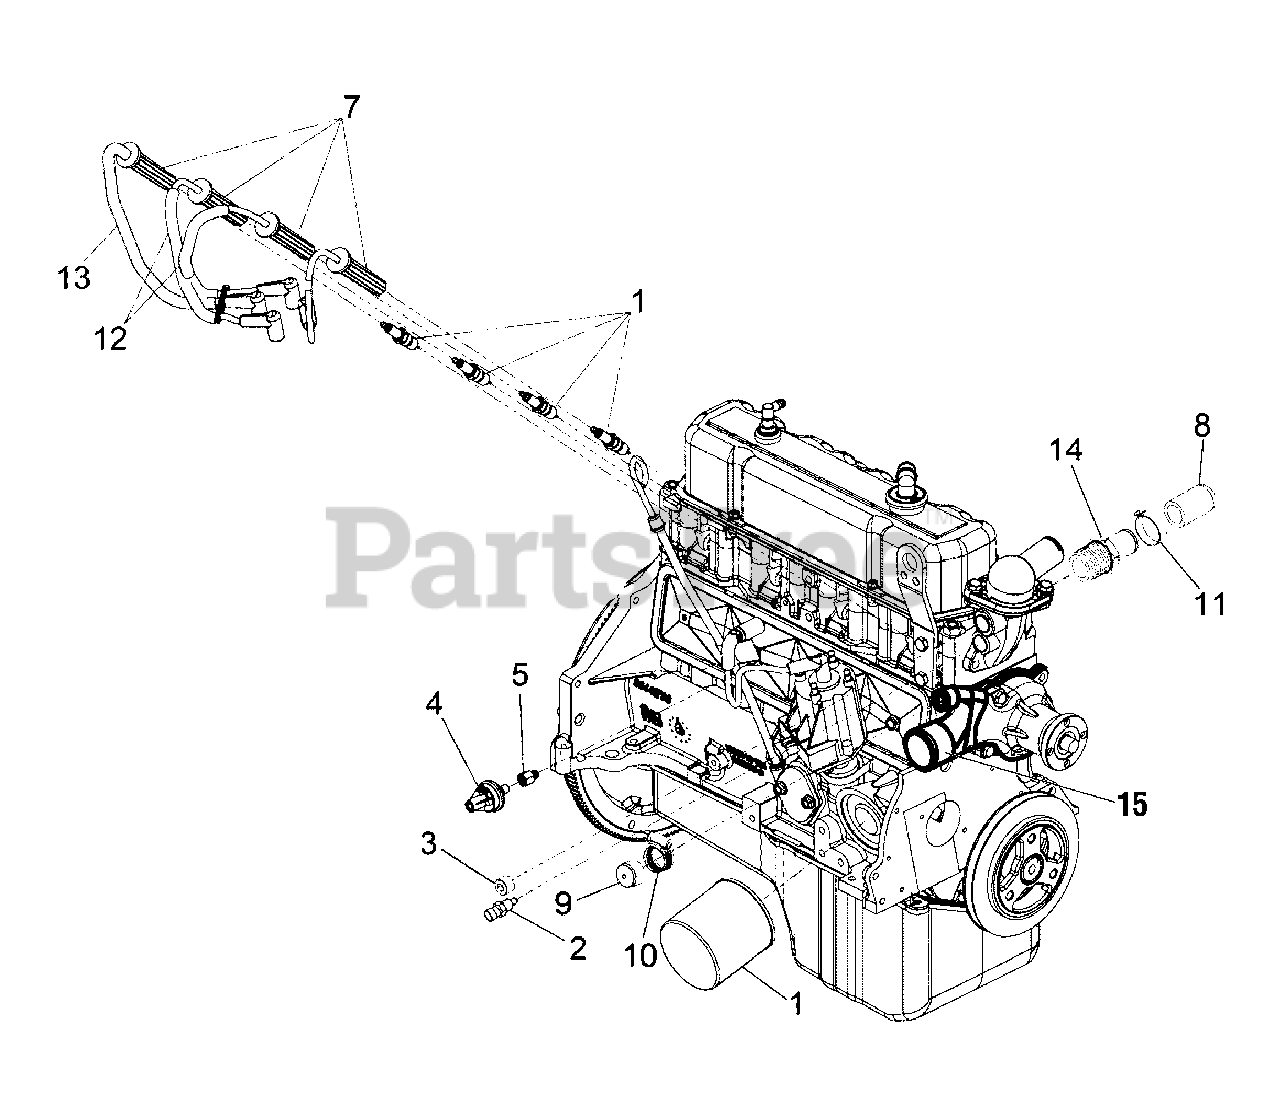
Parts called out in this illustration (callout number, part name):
1	KIT-MAINTENANCE
2	SENSOR
3	PLUG
5	PLUG
12	CONDUIT
13	CONDUIT
14	FITTING
